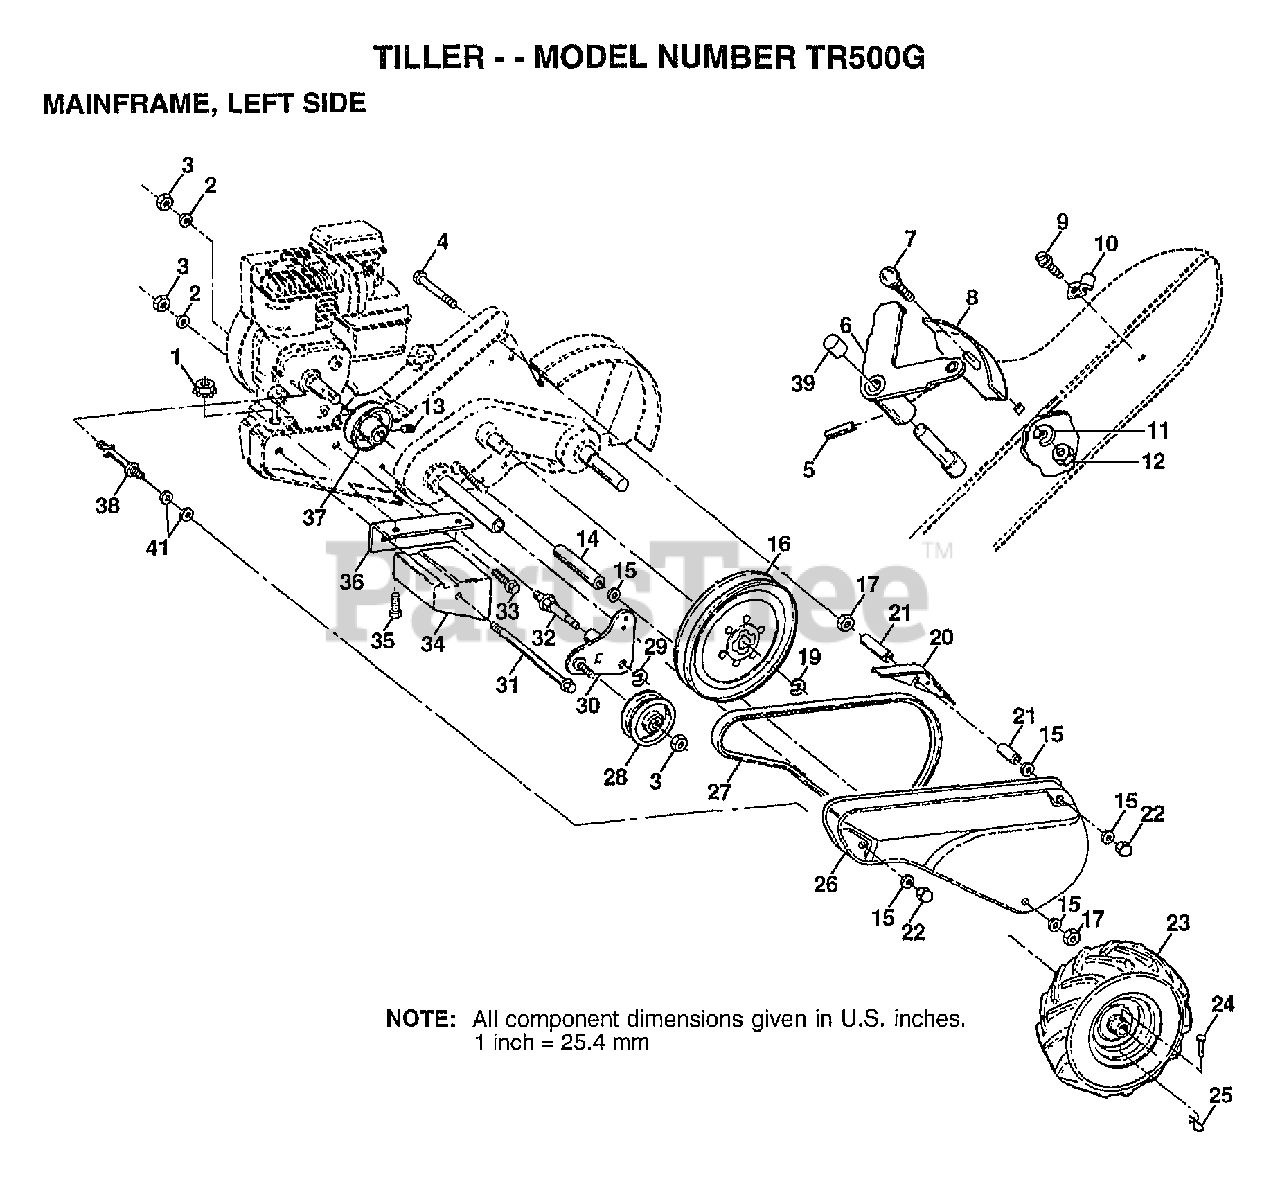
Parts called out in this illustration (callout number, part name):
2	LOCKWASHER
3	NUT.HEX.3/8-16UNC
4	BOLT TI
6	LEVER ASM CRT
7	BOLT
8	PANEL TI
10	CONDIUT CLIP T
11	LOCKWASHER
13	SET SCREW
14	SPACER
15	WASHER
16	SHEAVE.TRANS.
17	NUT.HEX.5/16-18
20	GUARD CRT
21	SPACER.SPLIT
22	NUT TI
23	TIRE.CHV.13X5.0-6
23	RIM
24	RIVET.DRILL.1.75
25	RETAINER M
26	GUARD.BELT.PNT.
27	BELT-V
28	PULLEY-IDLER TI
29	KLIP RING
31	BOLT CRT
32	SHIFT ARM CRT
33	BOLT
34	COUNTERWEIGHT CRT
35	BOLT.HEX.5/16-1.5
36	BRACKET LH CRT
37	ENGINE SHEAVE
38	STUD.GUARD.BELT
39	CAP PLUNGER BLACK
41	WASHER
